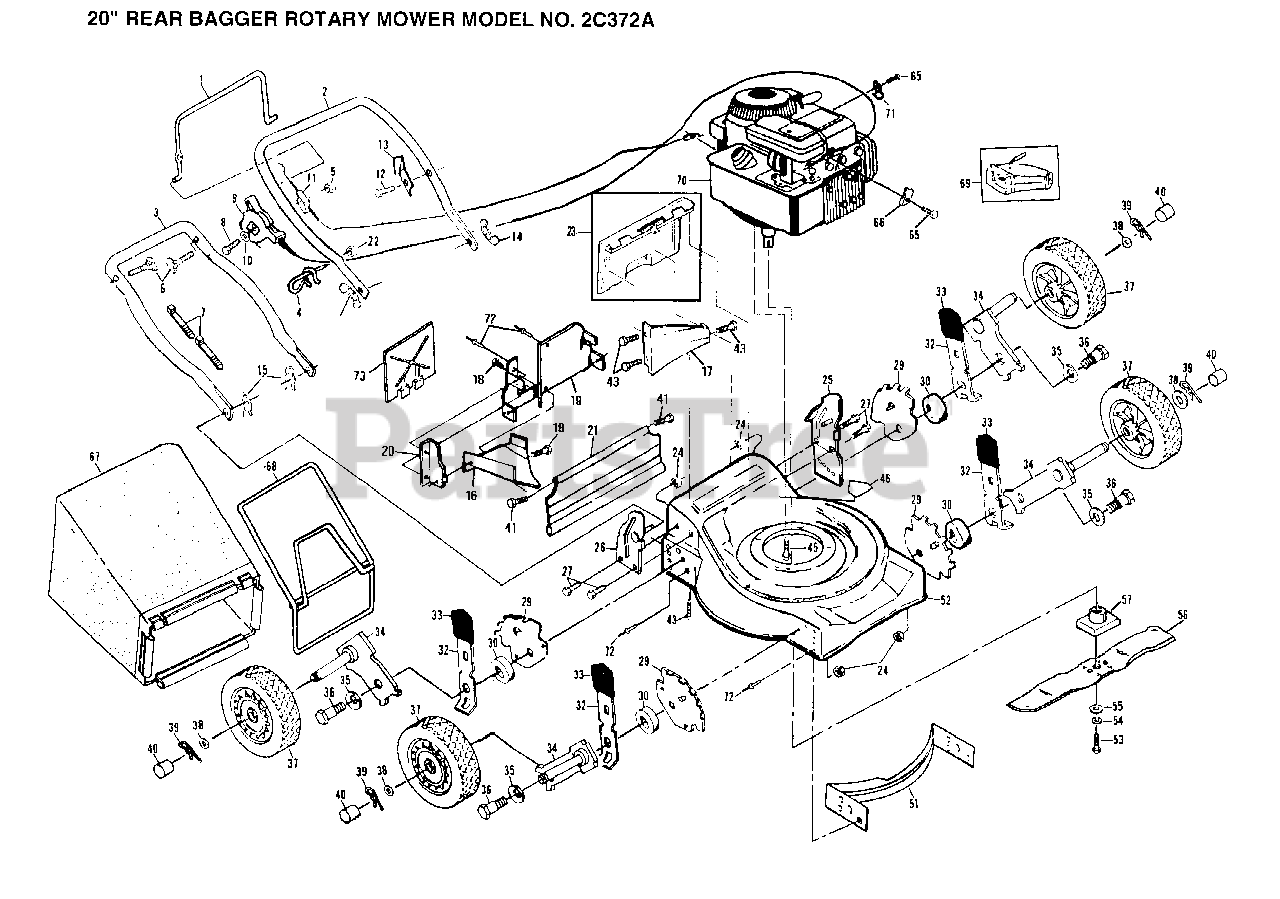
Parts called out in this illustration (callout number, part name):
1	CONTROL BAR
4	ROPE GUIDE
6	BOLT.HANDLE.LM
9	CONTROL THROTTLE
10	WASHER PM
11	"CABLE,ENG ZONE CO"
12	TAPPING SCREW
13	"BRKT,UPSTOP"
14	"NUT,WING PM"
15	HAIRPIN COTTER
16	DISCHARGE GUARD
17	REAR BAFFLE
18	SCREW PM
19	PLATE.BACK.20RD
22	NUT
23	"KIT, REAR DOOR PM"
24	LOCKNUT PM
27	SCREW
32	SPRING SELECTOR
33	KNOB PM
34	AXLE ARM
35	"WASHER, BELLEVIL."
38	WASHER
39	RETAINER CLIP PM
40	HUB CAP
41	HINGE SCREW
43	SCREW
45	SCREW
46	DECAL HYT
52	KIT.HSG.20RD
53	SCREW
54	LOCKWASHER
55	"WASHER,HARDEN"
57	BLADE ADAPTOR
65	SCREW PM
66	CABLE CLAMP
67	GRASS BAG
68	CATCHER FRAME
71	"CLIP,CABLE"
72	BLIND RIVET
73	MULCHER PLATE
